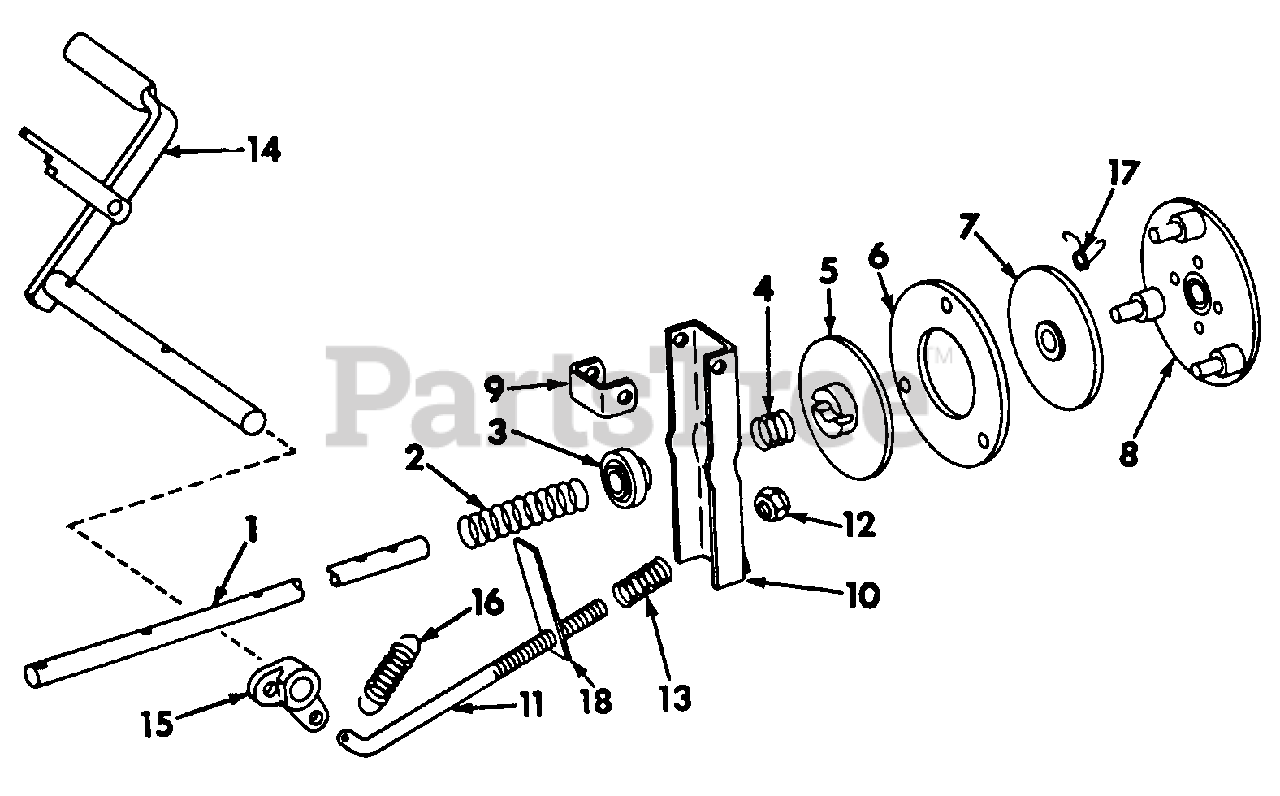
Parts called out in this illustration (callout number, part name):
1	Package, Clutch Shaft Service
2	Spring, Clutch Loading
3	Bearing, Clutch Throwout Ball
4	Spring, Clutch Teasing
5	Hub Assy, Pressure Plate
6	Disc, Clutch Driving
7	Hub Assy, Pressure Plate Locating
8	Plate Assy, Driving
9	Bracket, Clutch Operating Yoke
10	Lever, Clutch Release
11	Rod, Clutch Release
12	Nut, 3/8-24 Hex Self-Align
13	Spring, Clutch Release Rod
14	Pedal Assy, Clutch & Brake
15	Arm, Clutch & Brake Pedal
16	Spring, Clutch Pedal Return
17	Spring, Clutch Driving Disc
18	Strip, Safety Switch Release Lever
